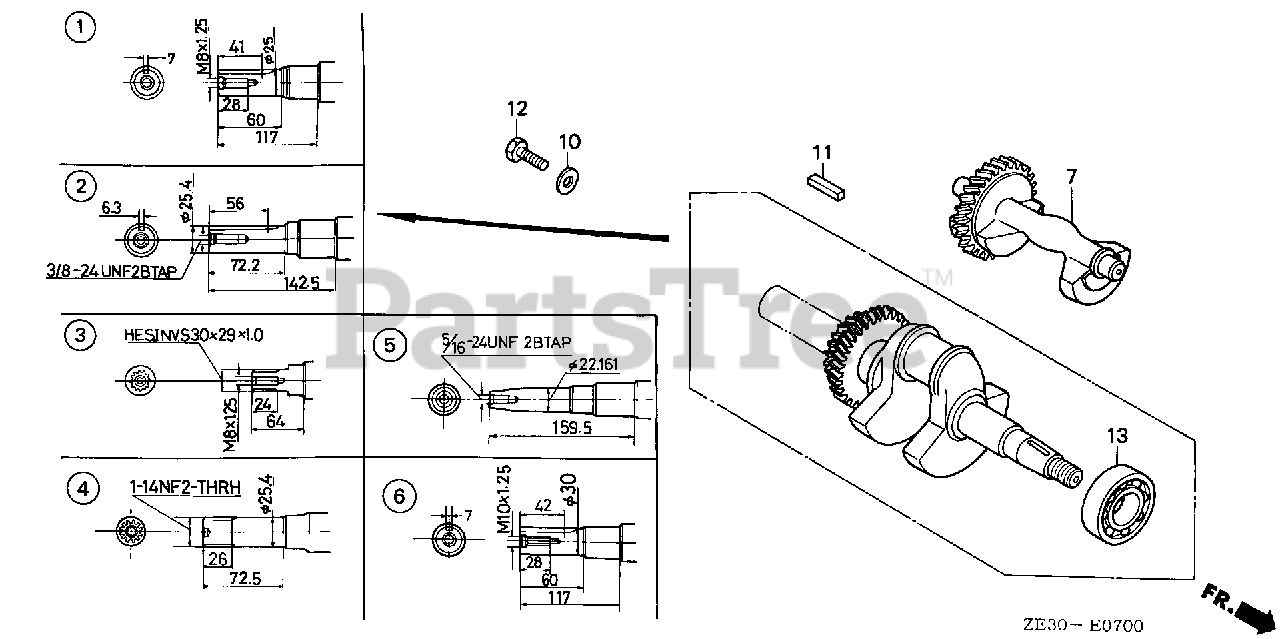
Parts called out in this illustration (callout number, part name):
3	CRANKSHAFT (NOT AVAILABLE)
3	CRANKSHAFT
7	WEIGHT, BALANCER (NOT AVAILABLE)
7	WEIGHT, BALANCER
13	BEARING, RADIAL BALL (6207)
